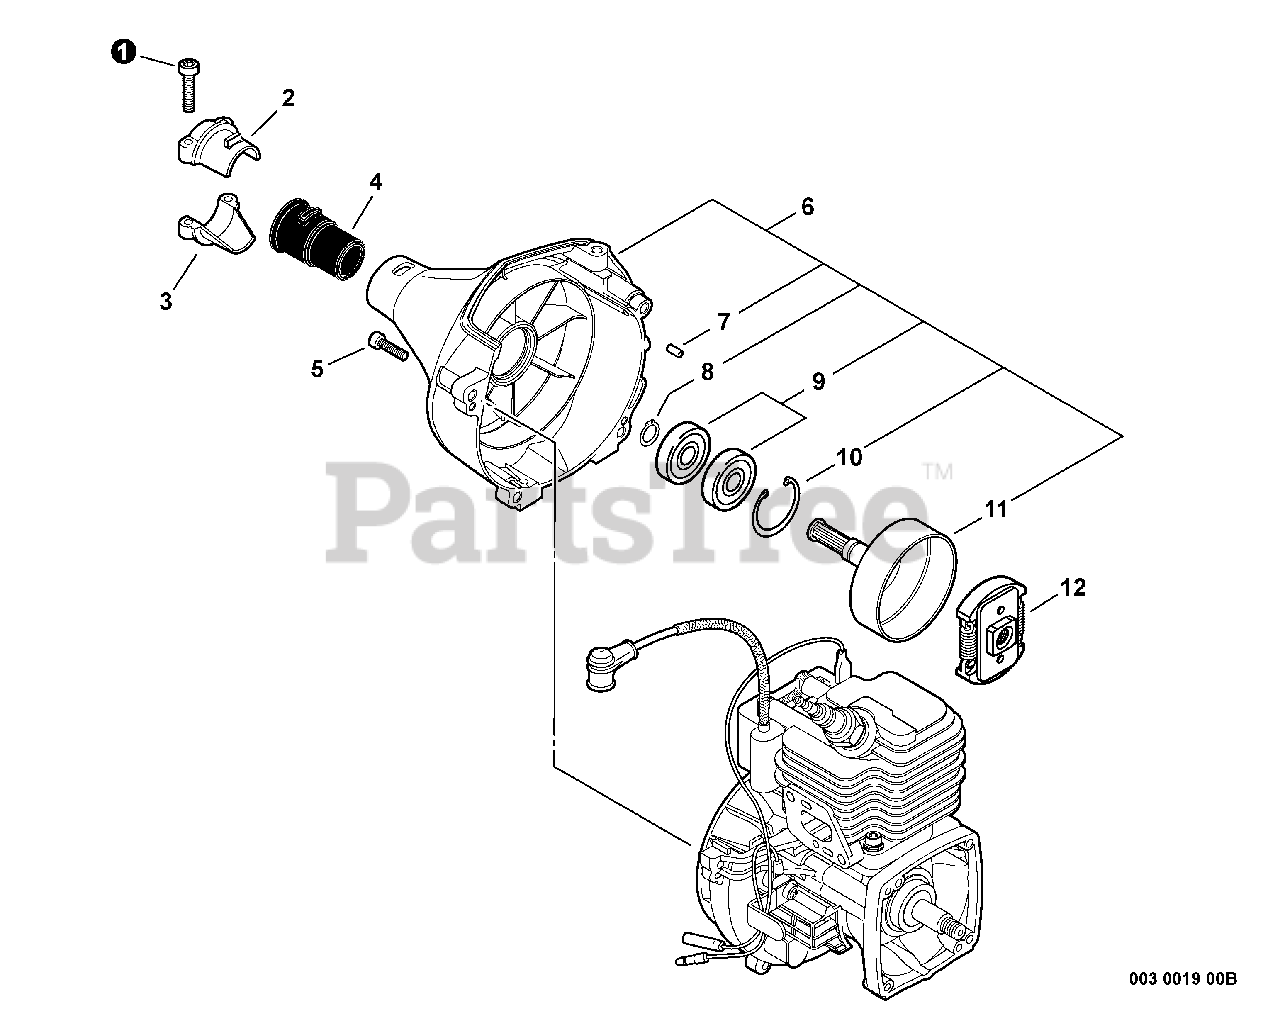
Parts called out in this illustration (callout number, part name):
1	SCREW - 5X20
2	CLAMP, MAIN PIPE - UPPER
3	CLAMP, MAIN PIPE - LOWER
5	SCREW - 4X16
6	FAN CASE ASSY
7	PIN - LOCATING
8	RING, RETAINING - 12
9	BEARING, BALL - 6001
10	RING, RETAINING - 28
11	DRUM, CLUTCH
12	CLUTCH ASSY
